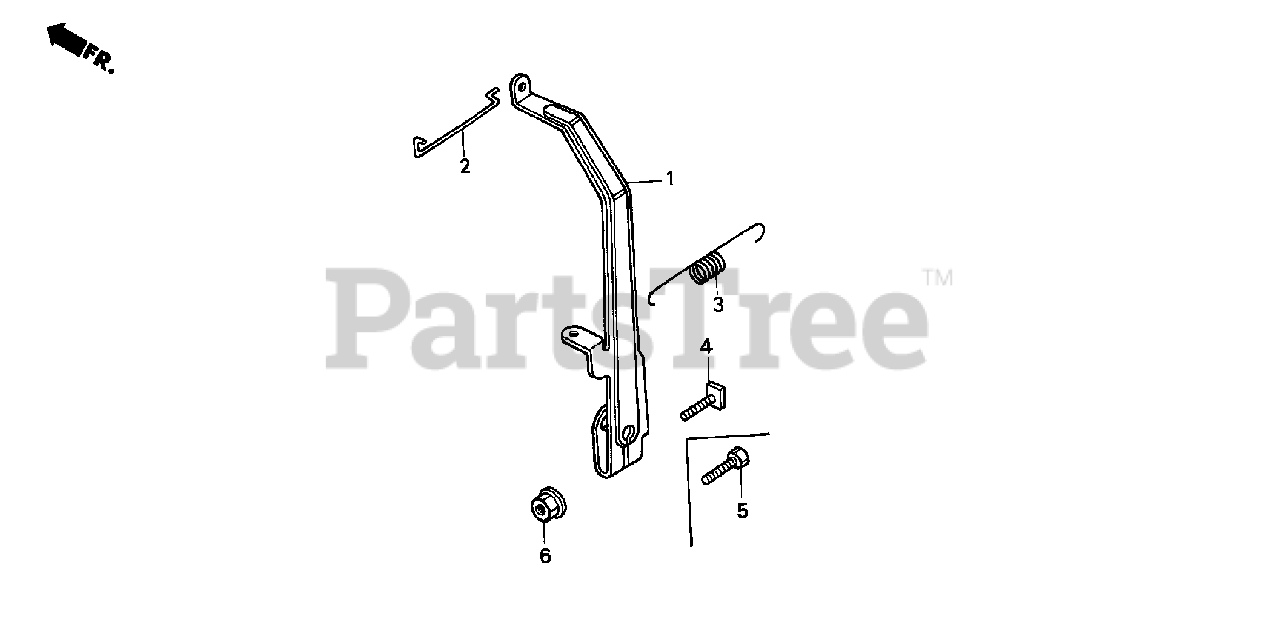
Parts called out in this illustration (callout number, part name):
1	ARM, GOVERNOR
2	ROD, GOVERNOR
3	SPRING, GOVERNOR
4	BOLT, GOVERNOR ARM
5	BOLT, HEX. (6X22)
6	NUT, FLANGE (6MM)
